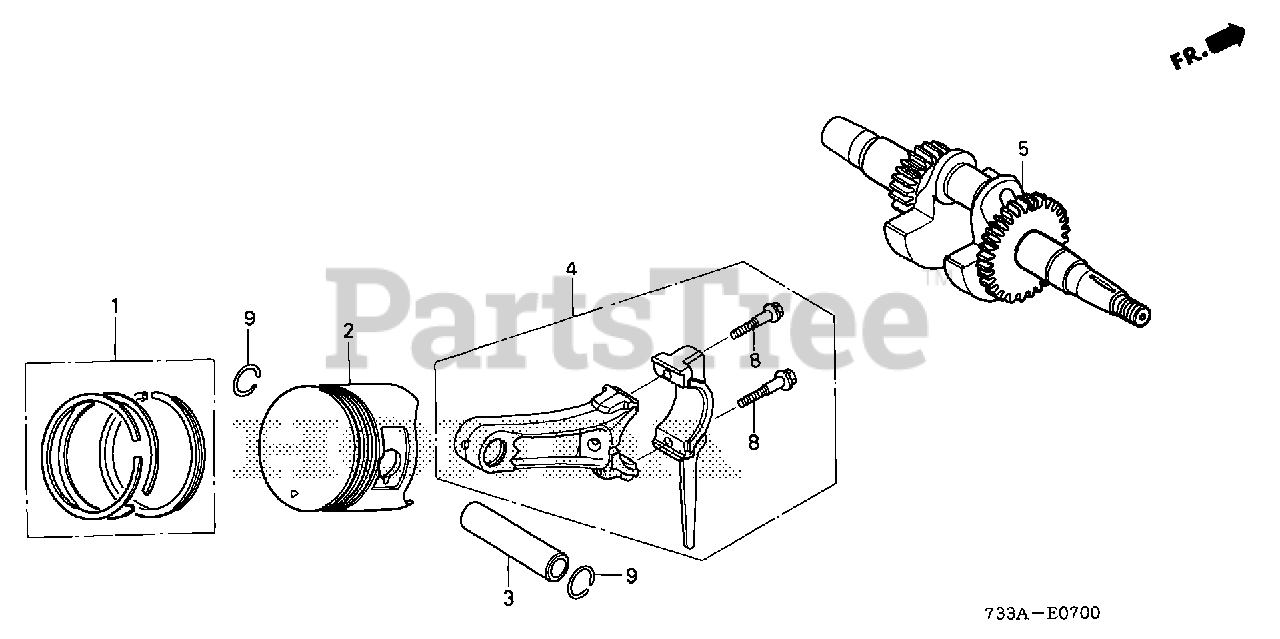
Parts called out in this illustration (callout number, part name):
1	RING SET, PISTON (STD) (NIPPON)
1	RING SET, PISTON (STD) (TEIKOKU)
1	RING SET, PISTON (0.25) (NIPPON)
1	RING SET, PISTON (0.25) (TEIKOKU)
1	RING SET, PISTON (0.50) (NIPPON)
1	RING SET, PISTON (0.50) (TEIKOKU)
1	RING SET, PISTON (0.75) (NIPPON)
1	RING SET, PISTON (0.75) (TEIKOKU)
1	RING SET, PISTON (0.75) (NIPPON) (NA USE ALT:13013-ZE1-014)
2	PISTON (STD)
2	PISTON (STD) (NOT AVAILABLE)
2	PISTON (0.25)
2	PISTON (0.25) (NOT AVAILABLE)
2	PISTON (0.50)
2	PISTON (0.75)
2	PISTON (0.75) (NOT AVAILABLE)
3	PIN, PISTON
4	ROD ASSY., CONNECTING (0.25 LOWER SIZE)
4	ROD ASSY., CONNECTING (STD)
4	ROD ASSY., CONNECTING (TH)
5	CRANKSHAFT (NOT AVAILABLE)
8	BOLT, CONNECTING ROD
9	CLIP, PISTON PIN (18MM)
